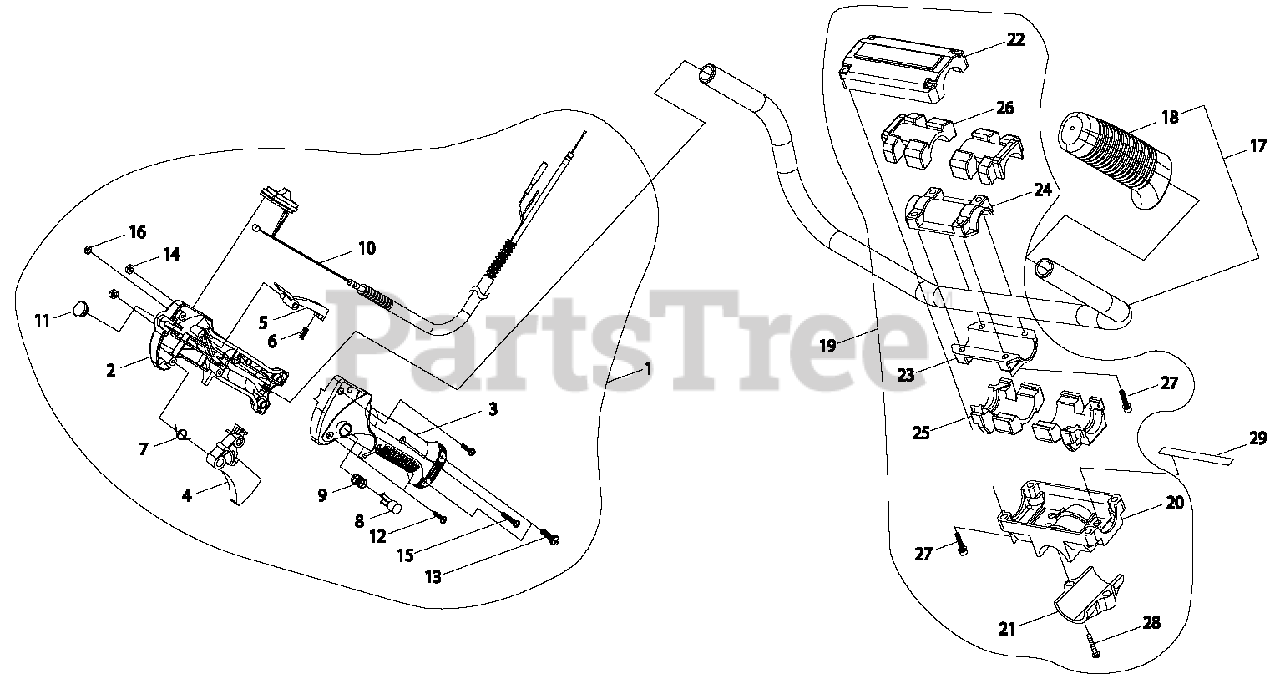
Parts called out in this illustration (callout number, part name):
1	THROTTLE CONTROL ASSY
2	CONTROL HANDLE - RIGHT
3	CONTROL HANDLE - LEFT
4	TRIGGER, THROTTLE
5	LOCKOUT, THROTTLE
6	SPRING, COMPRESSION
7	SPRING, TORSION
8	BUTTON, THROTTLE LOCK
9	SPRING, COMPRESSION
10	CABLE ASSY, CONTROL
11	PLUG, RUBBER
12	SCREW, TAPPING 4×16
13	SCREW, TAPPING 4×16
14	NUT M5
15	SCREW M4×23
16	NUT M4
17	HANDLEBAR ASSY
18	GRIP
19	BRACKET KIT, HANDLEBAR
20	BRACKET, HANDLE Ø28
21	CLAMP, LOWER Ø28
22	CLAMP, UPPER
23	CLAMP, LOWER
24	CLAMP, UPPER
25	CUSHION, LOWER
26	CUSHION, UPPER
27	BOLT M5×25
28	SCREW M6×25
29	LEAD - GROUND
